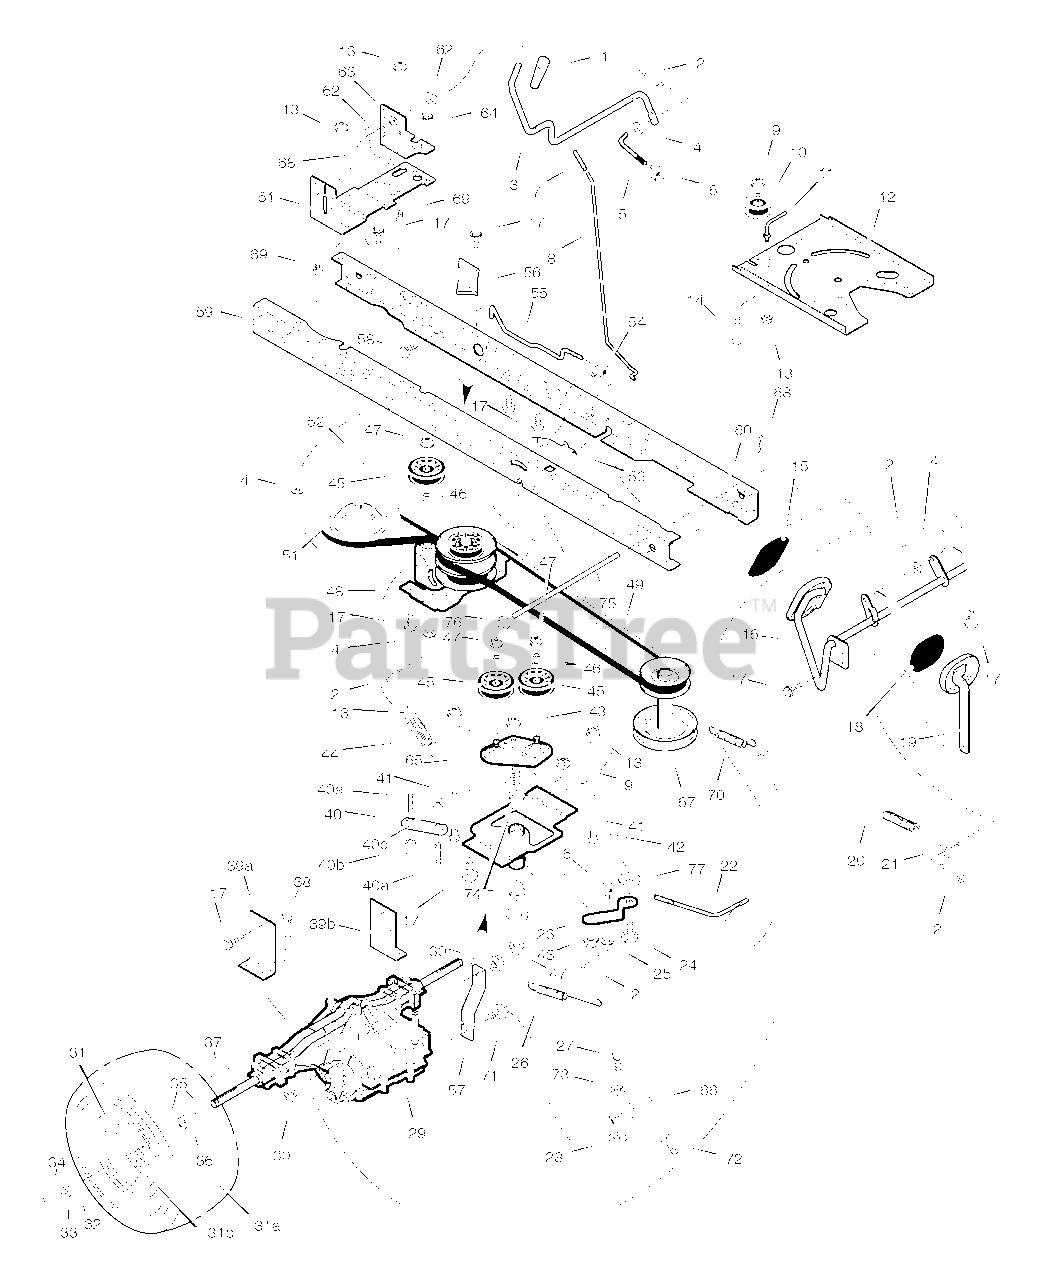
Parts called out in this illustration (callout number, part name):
1	Grip, Shift
2	Pin, Cotter
3	Lever, Shift
4	Washer
5	Link, Shifter
6	Nut, Adjuster
8	Rod, Parking Brake
9	Nut
10	Pulley, Idler
11	Guide, Belt
12	Plate, Steering
13	Nut
14	Bolt, Hex
15	Pad, Motion Drive
16	Assembly, Speed Control
17	Screw, Self Tapping
18	Pad, Brake Pedal
19	Assembly, Brake Pedal
20	Spring, Extension
21	Washer
22	Rod, Speed Control
23	Bellcrank
24	Bolt, Shoulder
26	Spring, Extension
27	Screw, Cap
29	Transaxle **
30	Nut
31	Assembly, Wheel and Tire
36	Spacer
37	Key, Square
38	Bolt, Hex
40	Link, Variator
41	Guide, Belt
42	Bracket, Front Frame
43	Nut, Lock
44	Spring, Extension
47	Nut
48	Assembly, Variator and Idler
49	Belt, Primary
50	Belt, Secondary
51	Pulley, Transaxle
52	Ring, Snap
53	Latch, Parking Brake
54	Nut, Adjusting
55	Rod, Clutch
56	Bracket, Brake
57	BRACKET, Torque Strap, LH
58	Screw
59	Rail, Right Frame
60	Rail, Left Frame
61	Bracket, Right Shift
62	Washer
63	Bracket, Shift Pivot
65	Assembly, Idler
66	Yoke, Shift
67	Pulley, Stack
68	Pin, Hair
69	Guide, Belt
70	Spring, Return
72	Pin, Hair
75	Rod, Belt Guide
76	Nut, Push-On
